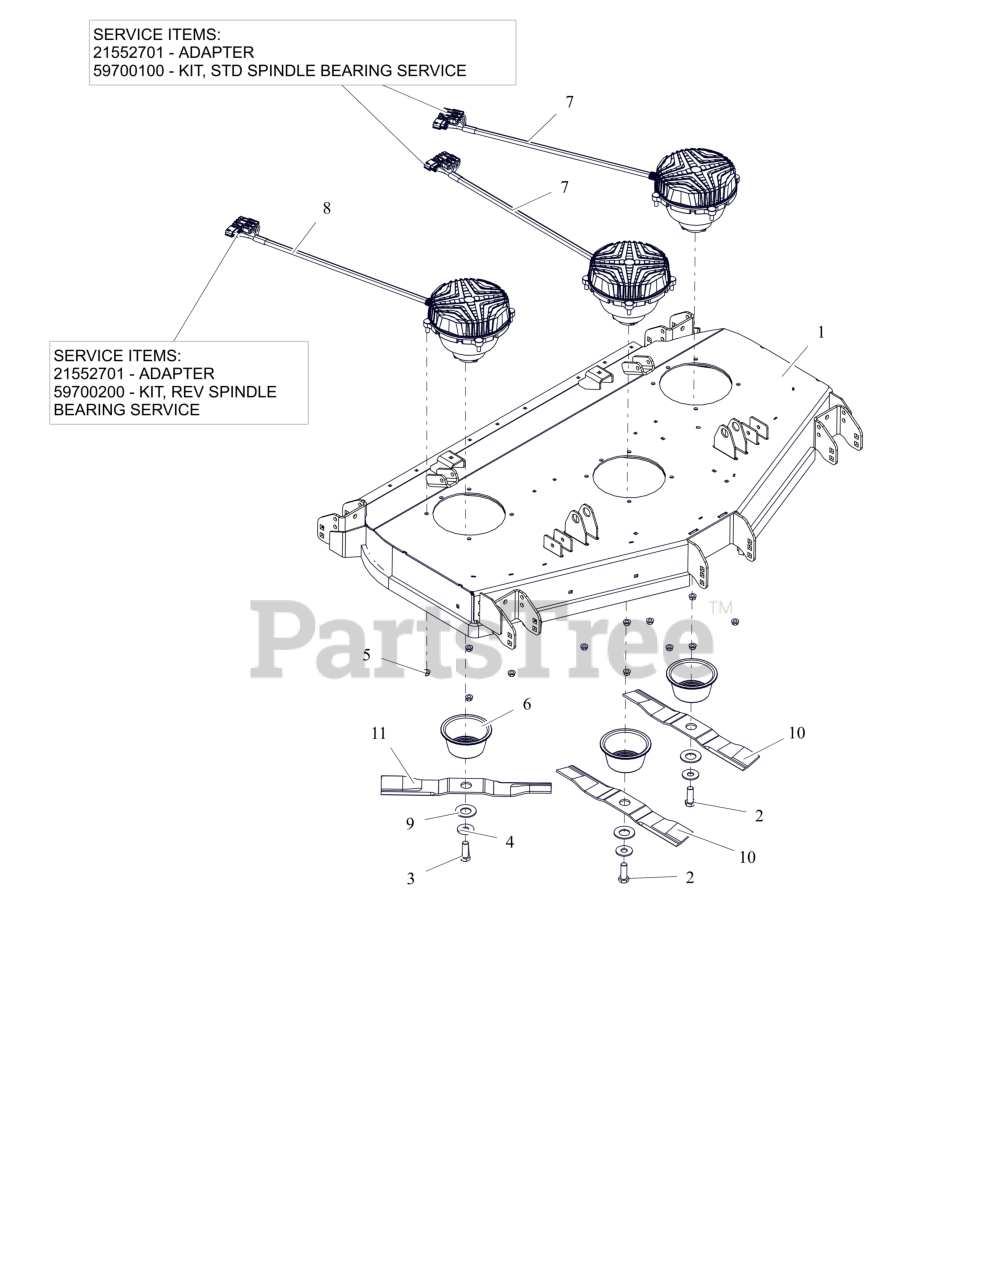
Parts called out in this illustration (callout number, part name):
1	KIT,DECK 52 RD W/DECALS-A
2	BLT, HEX .62-18X1.75 G8 ZCC
3	BLT, HEX 0.625-11X1.75 GR8 ZCC LH
4	WSHR, HRDN 0.687X1.75X0.134 HRD
5	NUT-LK-CTR-FLG .375-16 GF ZCC
6	GUARD, SPINDLE LOWER
7	MOTOR, DECK - 48"/52" CW
7	ADAPTER
7	KIT,STD SPINDLE BEARING SERVICE
8	MOTOR, DECK - 48"/52" CCW
8	ADAPTER
8	KIT,REV SPINDLE BEARING SERVICE
9	WSHR, BLVL - .56X28.5X3 PHOS.COAT
10	BLADE- MOWER-18.00" LOW
11	BLADE, MOWER -18.00" EFF CCW
